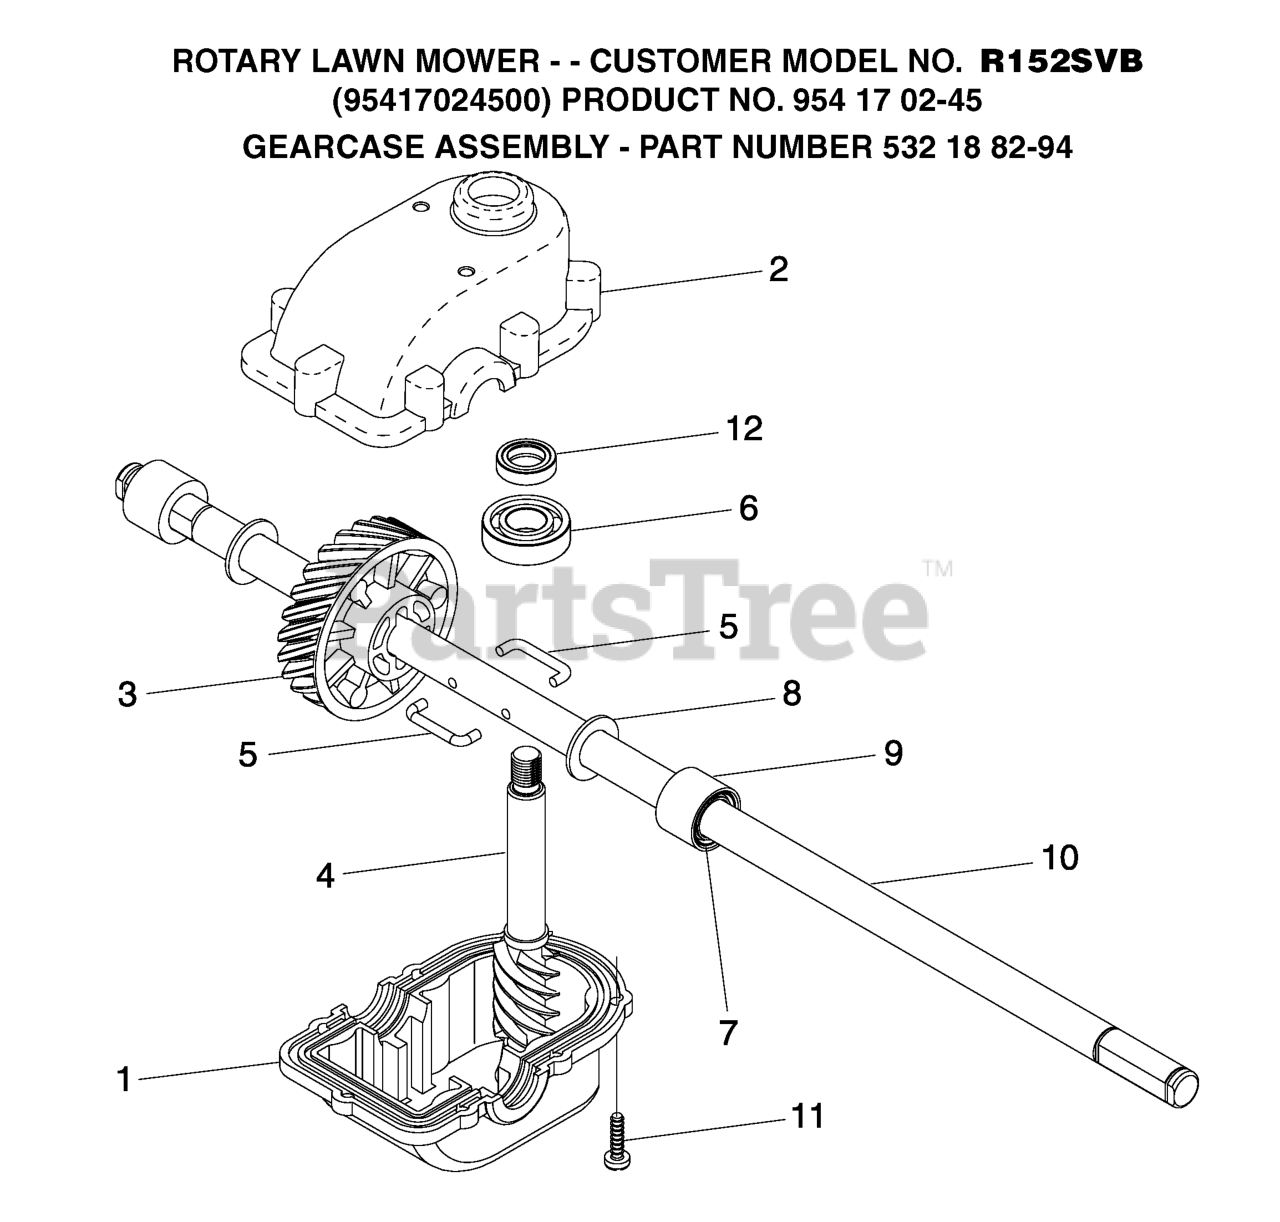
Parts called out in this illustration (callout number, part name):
1	CASE, LOWER
2	GEARCASE.HOUSING
3	GEAR.24.TOOTH.WALK.MOWER
5	WIRE, FORMED (15966)
7	SEAL.OUTPUT.SHAFT
10	SHAFT OUTPUT
12	SEAL INPUT SHAFT
